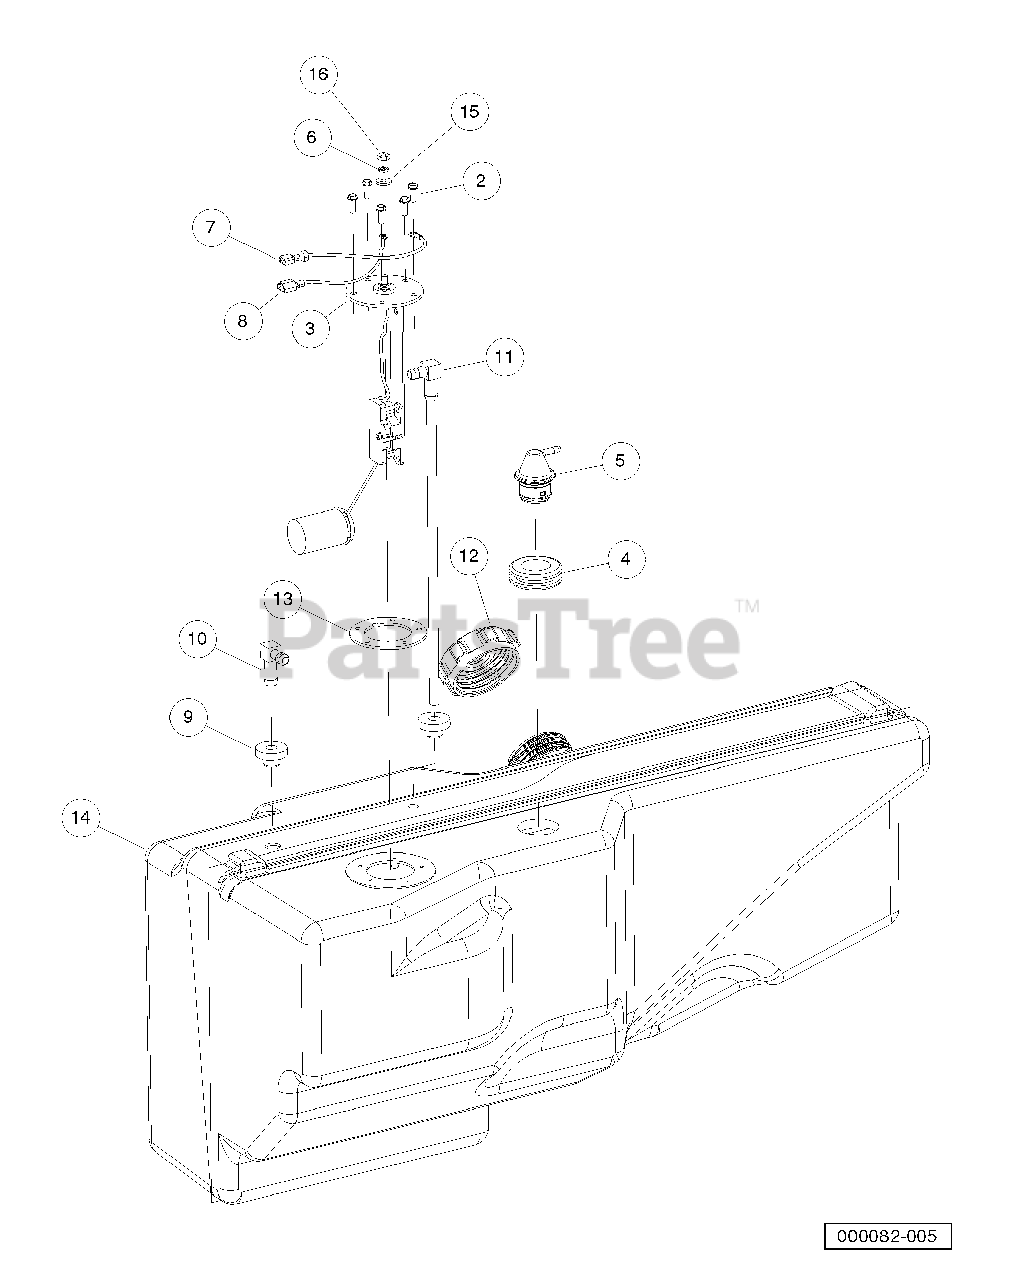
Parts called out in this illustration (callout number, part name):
1	Asm, Tank, Fuel, Diesel, 4x4
2	Screw, #10-16 Hex-Head Hi-Lo
3	Sending Unit, Fuel Level
4	Insulation Grommet
5	Vent, Fuel Tank
6	Washer, #10 Split Lock
9	Bushing, Line, Return
10	Elbow, 90 Barbed
11	Pickup Tube, Fuel
12	Cap, Fuel
13	Gasket, Rubber
15	Washer, #10 Type A Flat
16	Nut, #10-32 Brass Hex
